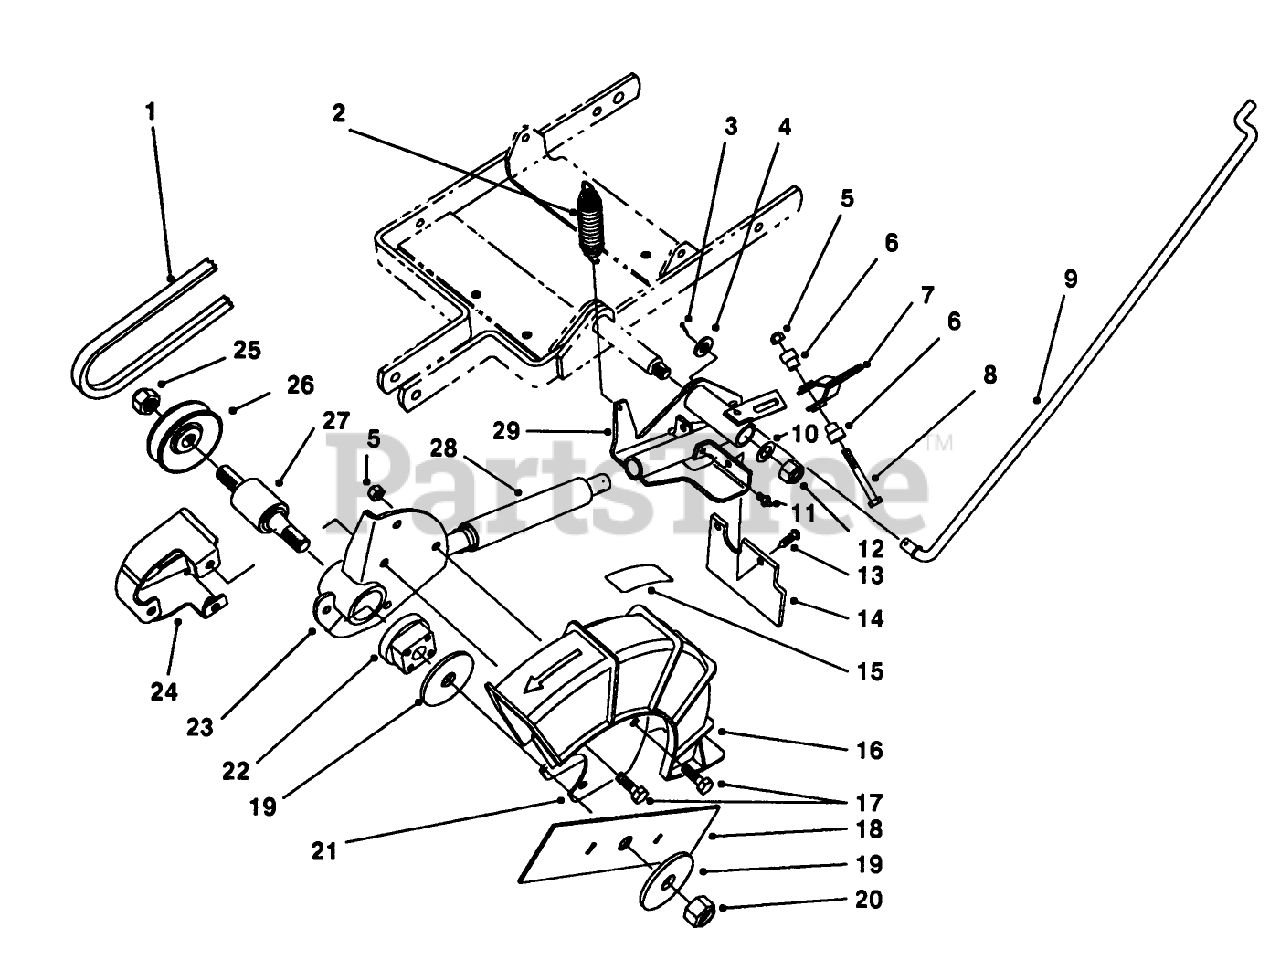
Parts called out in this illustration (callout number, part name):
2	EXT. SPRING
3	PIN-COTTER
4	WASHER-FLAT
5	NUT-LOCK, NI
7	LEVER WA *
8	SCREW-HH
9	LOWER CONTROL ROD *
10	WASHER-PLAIN
11	FITTING-GREASE
12	NUT-LOCK, NI
14	RUBBER GUARD
17	SCREW-HWHTF
18	9" EDGER BLADE*
19	WASHER-LARGE
20	NUT-HEX
23	HUB ASM *
25	NUT-LOCK, NI
28	SPRING & BELLOW ASM
29	PIVOT ARM WA *
